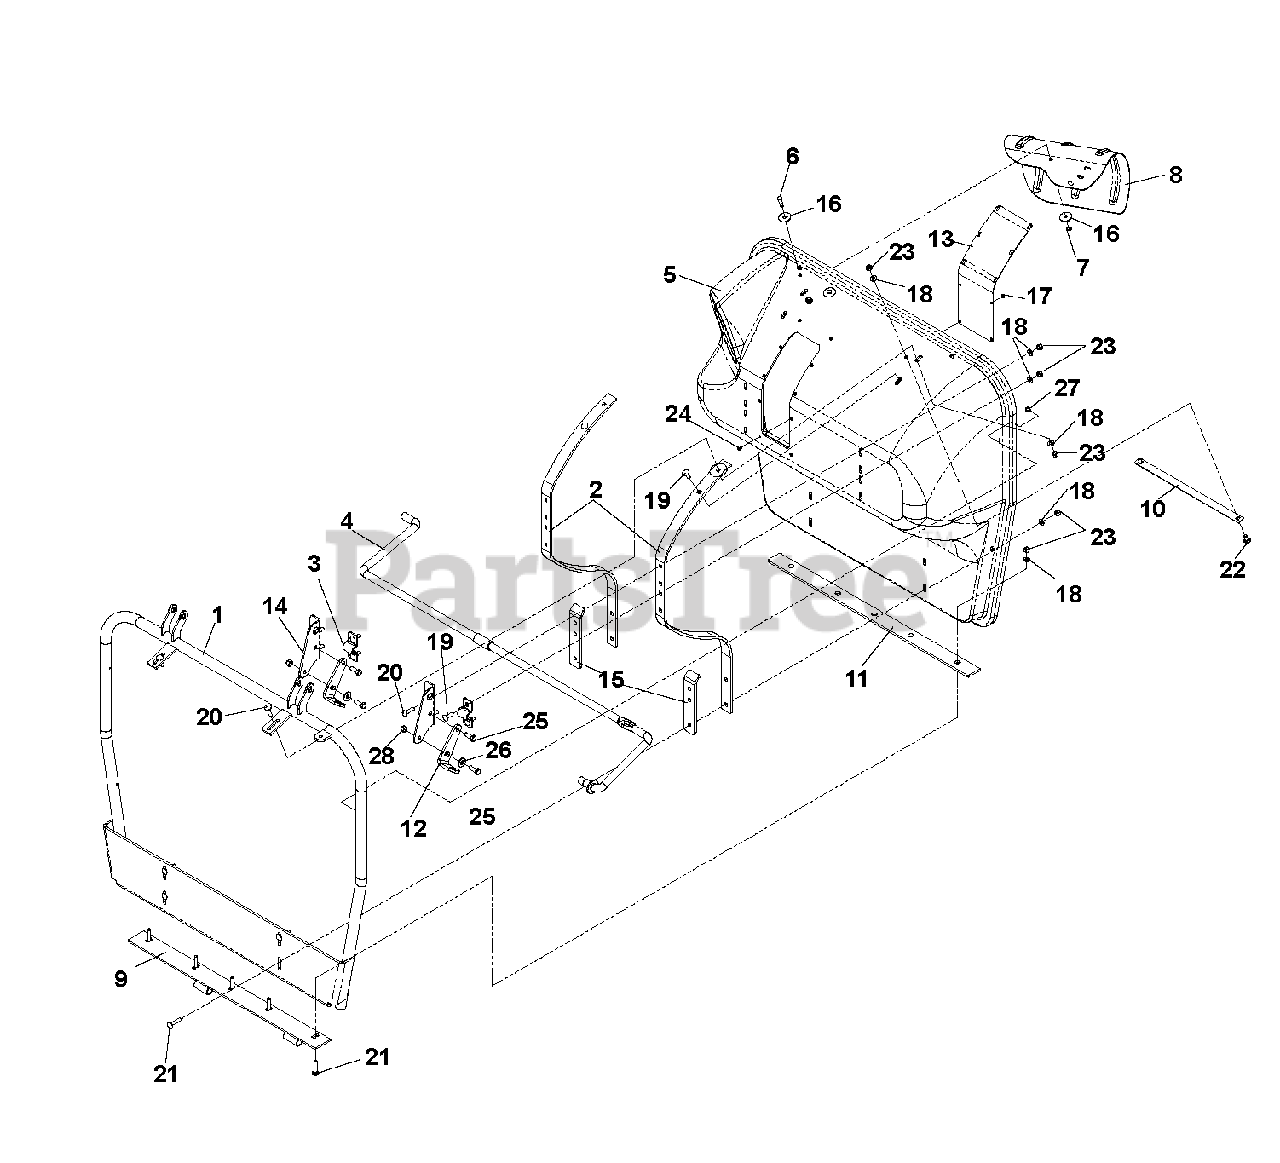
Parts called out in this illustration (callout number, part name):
1	FRONT FRAME WLDT.
4	LIFT SHAFT
5	CLAM SHELL (FRONT)
6	CLEVIS PIN 5/16
7	RETAINER RING
8	DEFLECTOR
9	MOUNT.LOWER.CLAMSHELL
11	CLAMSHELL SPACER
12	BRACKET, SUPPORT
14	BRKT, SUPPORT, UPPER
15	CLAMSHELL SUPPORT PLATE
16	WASHER, FENDER 5/16
17	5/8-11 HEX NUT
18	FLAT WASHER 5/16 SAE
19	RHSSNB 5/16C X 1.0
20	BOLT, CARRIAGE 5/16X1-1/4
21	RHSNB 5/16-18 X 1-1/2 GR 5 ZD
22	BOLT 5/16C X 3/4" CARRIAGE
23	NUT 5/16 NYLOC
24	POP RIVET 5/32 STEEL
25	HCS 3/8C X 1
26	WASHER 3/8 FLAT
27	LARGE DOME RIVET
28	NUT 3/8-16 NYLOC
